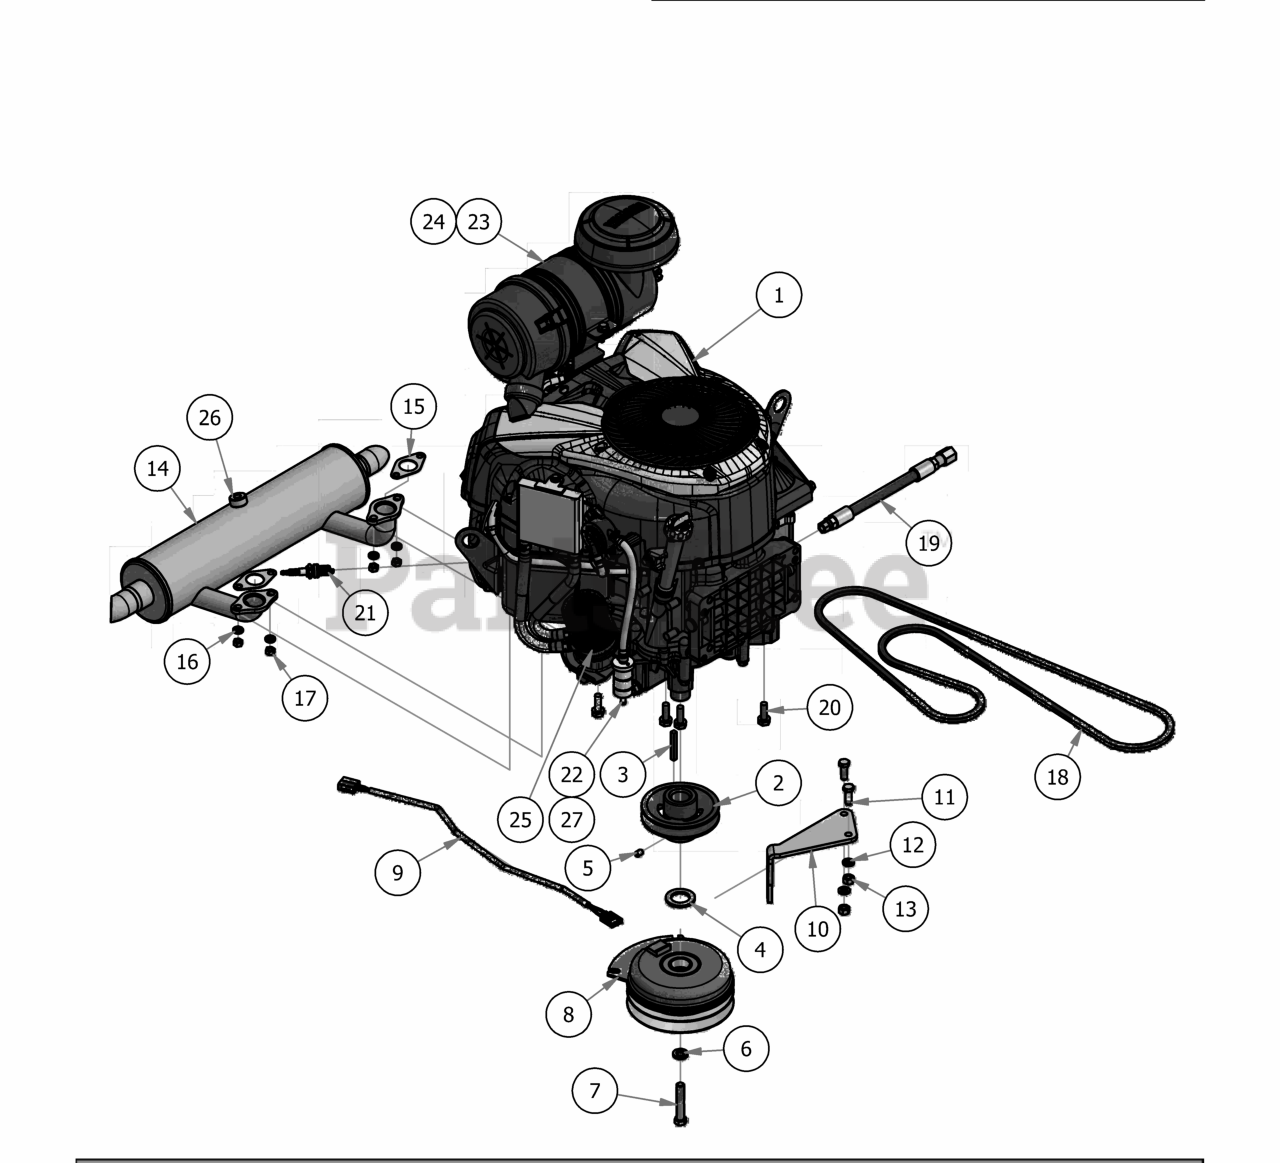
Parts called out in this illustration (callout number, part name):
1	Carbureted 27.5hp Yamaha Engine
2	4 3/4 Motor Pulley
3	1/4 x 2 Square key Stock
4	1 1/8" Flat Spacer
5	3/8" Set Screw
6	7/16" Lock Washer
7	7/16" x 2 1/2" Hex Bolt
8	Clutch Assembly
9	Clutch Pigtail
10	PTO Engager Holder
11	3/8" x 1" Hex Bolt
12	3/8" Lock Washer
13	3/8" Hex Nut
14	Yamaha Muffler
15	Exhaust Gasket for yamaha
16	5/16" Lock Washer
17	M8-1.25 Zinc Nut
18	Pump Belt Diesel
19	Oil drain Hose for Yamaha
20	3/8 x 1 1/8 bolt
21	Spark Plug - Yamaha
22	Universal Inline Fuel Filter
23	Canister Air Filter- Outer
24	Canister Air Filter- Inner
25	Oil Filter
26	O2 Sensor Plug
27	Yamaha Fuel Filter
